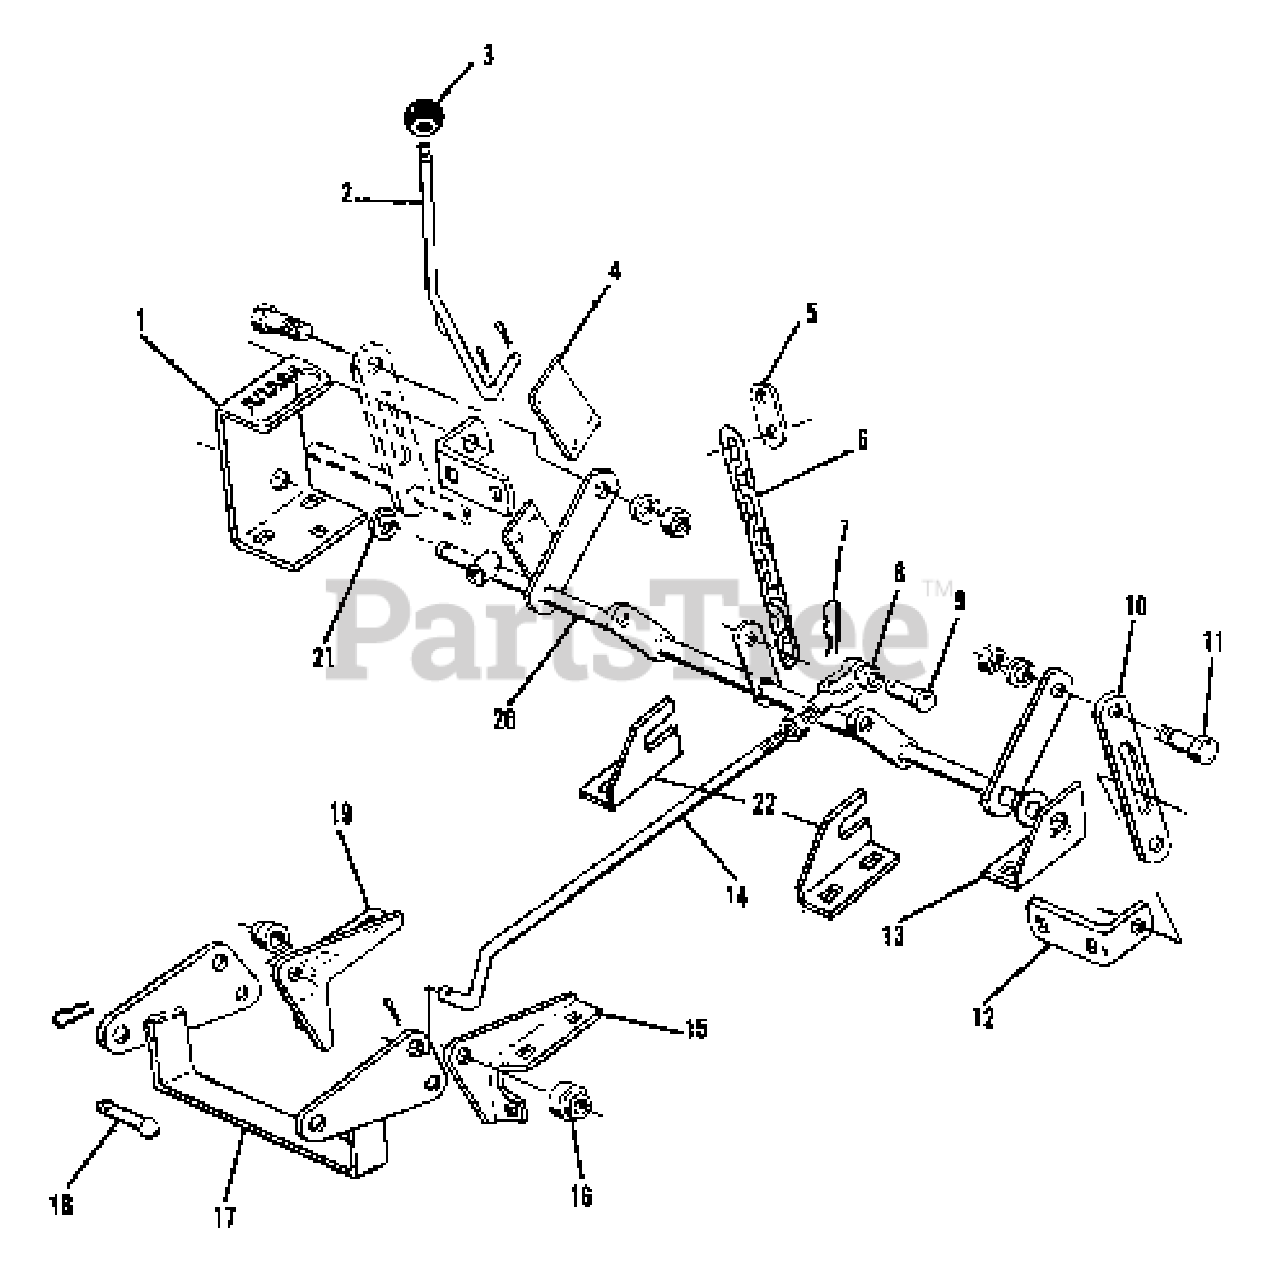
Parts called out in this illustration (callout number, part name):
1	QUADRANT, Control
1	DECAL, Quadrant
1	CARRIAGE BOLT, 3/8NC x 3/4
1	LOCKWASHER, 3/8
1	NUT, 3/8NC
2	LEVER, Control (42" Mower - Prior to S/N 04105383: 48" Mower - Prior to S/N 04203607)
2	LEVER, Control (42" Mower - Effective. w/S/N 04105383 & Up: 48" Mower - Effective w/S/N 04203607 & Up)
2	PIN, Cotter, 1/8 x 1
3	KNOB, Control Lever
4	SPRING, Lever Retaining
4	RIVET, Pop, 3/16
5	LINK, Lift
5	CAPSCREW, 3/8 NC x 1
5	WASHER, Plain, 7/16 x 1 x #14
5	NUT, Lock, 3/8NC
6	CHAIN, Lift
6	CAPSCREW, 3/8 NC x 1-1/4
6	WASHER, Plain 7/16 x 1 x #14
6	LOCKWASHER, 3/8
6	NUT, 3/8NC
7	PIN, Quick-Hitch
8	YOKE, Rod
9	PIN, Yoke
10	BAR, Roller Lift
11	BOLT, Shoulder, 3/8-16 X 1.34
11	WASHER, Plain, 1/2 x 1-1/4 x #14
11	LOCKWASHER, 3/8
11	NUT, 3/8NC
12	BRACKET, Roller Support
12	CARRIAGE BOLT, 3/8NC x 3/4
12	CARRIAGE BOLT, 3/8NC x 1
12	LOCKWASHER, 3/8
12	NUT, 3/8NC
13	BRACKET, Pivot, L.H.
13	CARRIAGE BOLT, 3/8 NC x 3/4
13	LOCKWASHER, 3/8
13	NUT, 3/8NC
14	ROD, Adjusting, R.H. (F/42" Mower)
14	ROD, Adjusting, L.H. (F/42" Mower)
14	ROD, Adjusting, R.H. (F/48" Mower)
14	ROD, Adjusting, L.H. (F/48" Mower)
14	PIN, Cotter, 1/8 x 1
14	NUT, Jam, 1/2 NF
15	BRACKET, Link, L.H.
15	CARRIAGE BOLT, 3/8 NC x 3/4
15	LOCKWASHER, 3/8
15	WASHER, 17/32 x 1-1/4 x 16GA
16	SPACER, Pivot, Shouldered
17	LINK ASSEMBLY, Pivot
17	CAPSCREW, 3/8 NC x 1-3/4
17	WASHER, Plain, 13/32 x 1 x #10
17	LOCKWASHER, 3/8
17	NUT, 3/8NC
18	PIN, Link
19	BRACKET, Link, R.H.
19	CARRIAGE BOLT, 3/8 NC x 3/4
19	LOCKWASHER, 3/8
19	WASHER, 17/32 x 1-1/4 x 16GA
20	ARM ASSEMBLY, Adjusting
20	WASHER, Plain, 25/32 x 1-1/4 x #16
21	RING, Retaining
22	SUPPORT, R.H. Shaft
22	SUPPORT, L.H. Shaft
22	BOLT, 5/16NC x 1
22	LOCKWASHER, 5/16
22	NUT, 5/16NC
